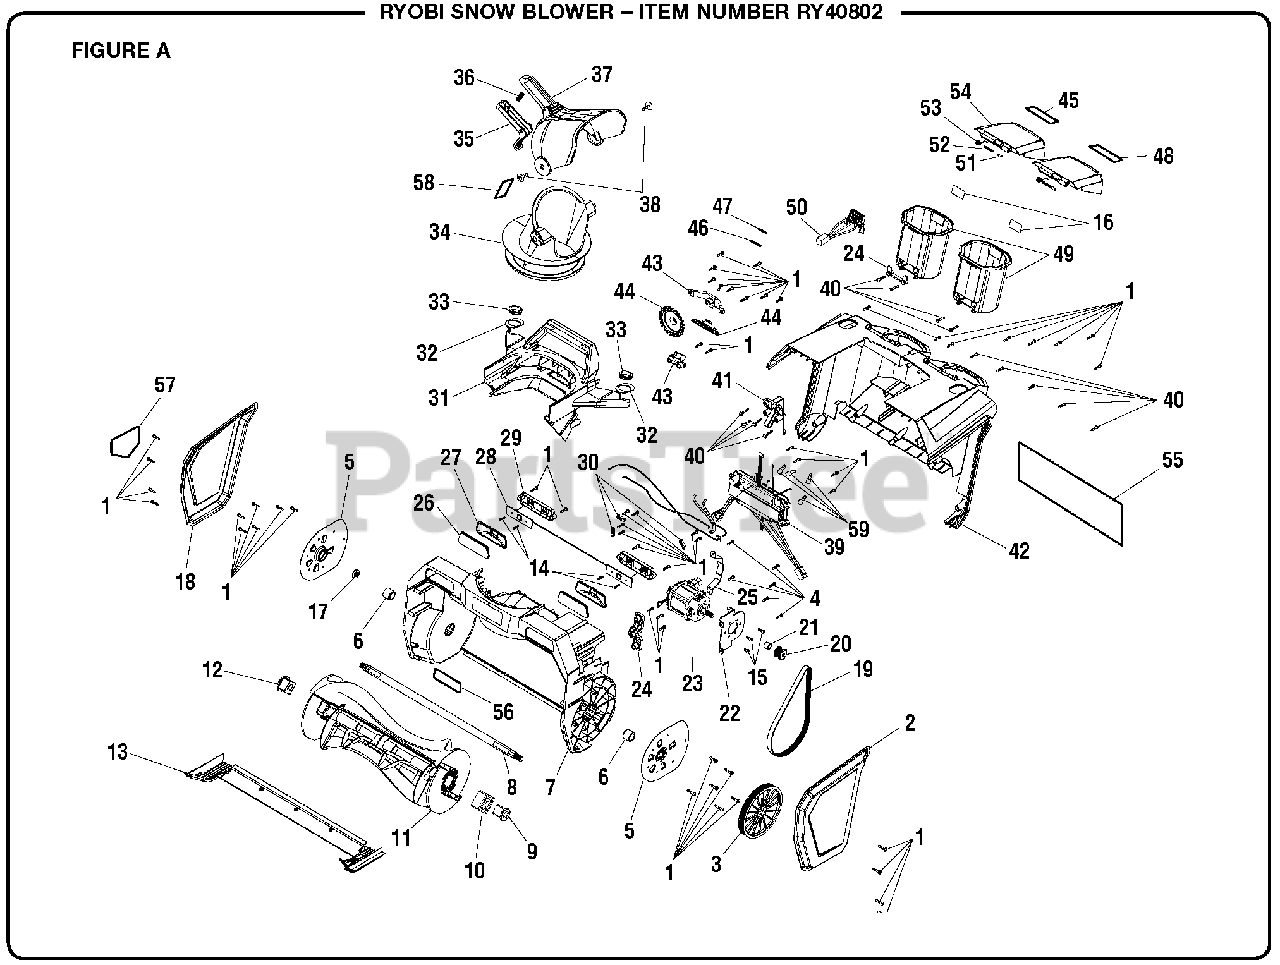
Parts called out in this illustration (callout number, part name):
1	Screw (4 x 18 mm, T15 Torx Pan Hd.)
2	Left Side Cover
4	Screw (M4-18 x 30 mm, T15 Torx Soc. Hd.)
5	Bearing Plate w/Bearing Assembly
7	Front Housing Assembly
8	Auger Shaft
9	Left Drive Block
10	Connect Plate
12	Right Drive Block
13	Scraper Blade Assembly
14	Screw (M3-24 x 8 mm, Pan Hd.)
15	Screw w/Washer (M5 x 8 mm, Pan Hd.)
16	Battery Temperature Label
17	Hex Nut (M12)
18	Right Cover Assembly
19	V-Belt (Type 5EPJ568)
20	Drive Pulley
21	Motor Bushing
22	Motor Locating Plate
24	Motor Support & Terminal Holder Assembly
25	Motor Plate
26	Headlight Lens
27	Reflector
28	LED Light Plate Assembly (Set of 2)
29	Fixing Plate (LED Lens)
30	Cord Clamp
31	Carry Handle
33	Rubber Bushing
35	Nozzle Adjustment Handle
36	Compression Spring
37	Chute Nozzle Assembly
38	Screw w/Washer (M4-18 x 10 mm, T20 Torx Pan Hd.)
39	Brushless Motor Controller
40	Screw (M4 x 20 mm, T20 Torx Pan Hd.)
41	Fixing Plate (Chute Rod)
42	Rear Housing Assembly
43	Gear Support Assembly
44	Gear Assembly
45	On-Board Storage Label
46	Washer (ID 17.5 x OD24 x 1t)
48	In-Use Label
49	Battery Carriage
50	Battery Holder Assembly
52	Compression Spring
53	Torsion Spring
54	Battery Cover Assembly
55	Danger/Data Label
56	Front Logo Label
57	CPSC Label
58	Chute Icon Label
59	Wire Connector
